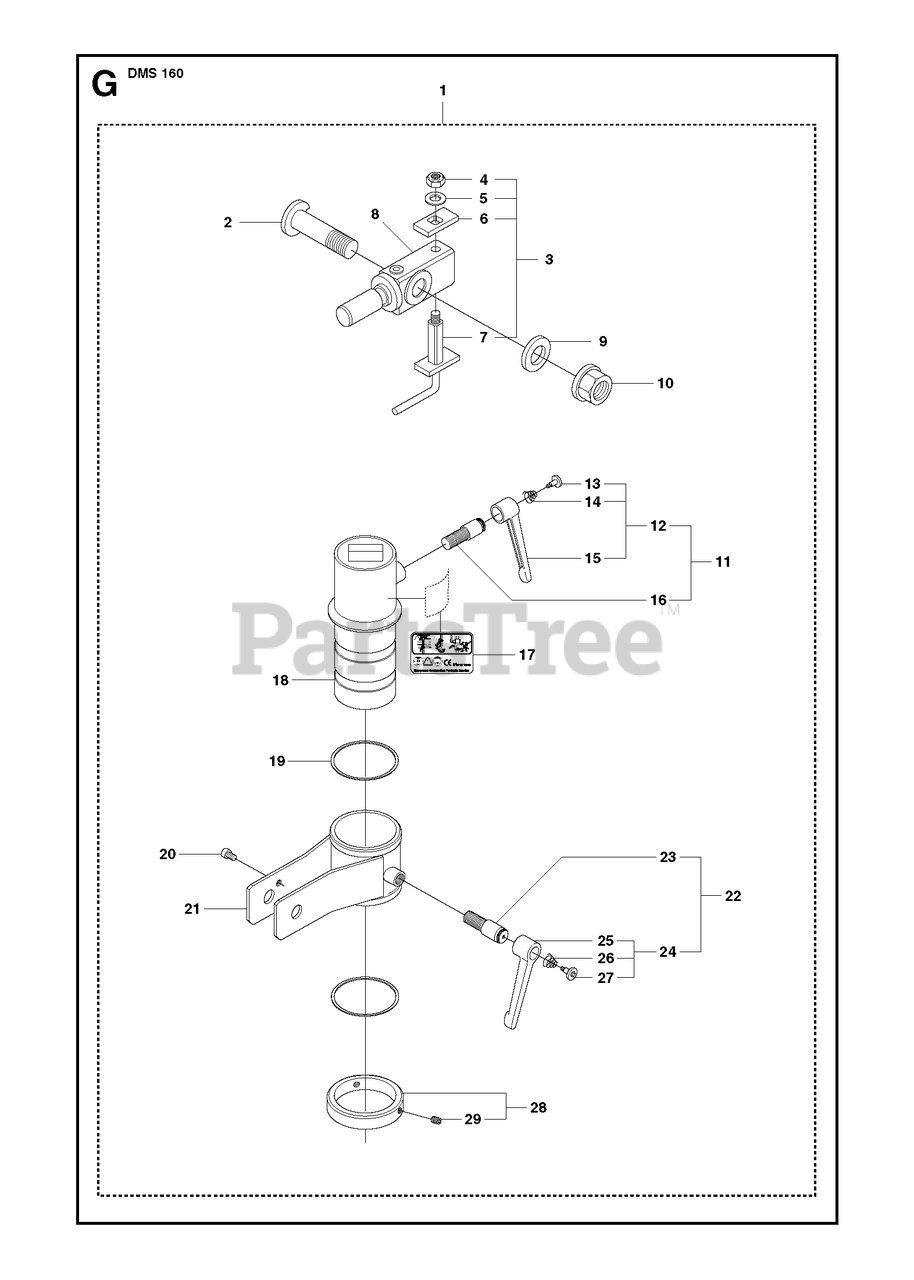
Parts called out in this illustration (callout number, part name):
1	BRACKET GYROIncl. 2, 3, 8-11, 17-22, 28
12	HANDLEIncl. 13-15
24	HANDLEIncl. 25-27
